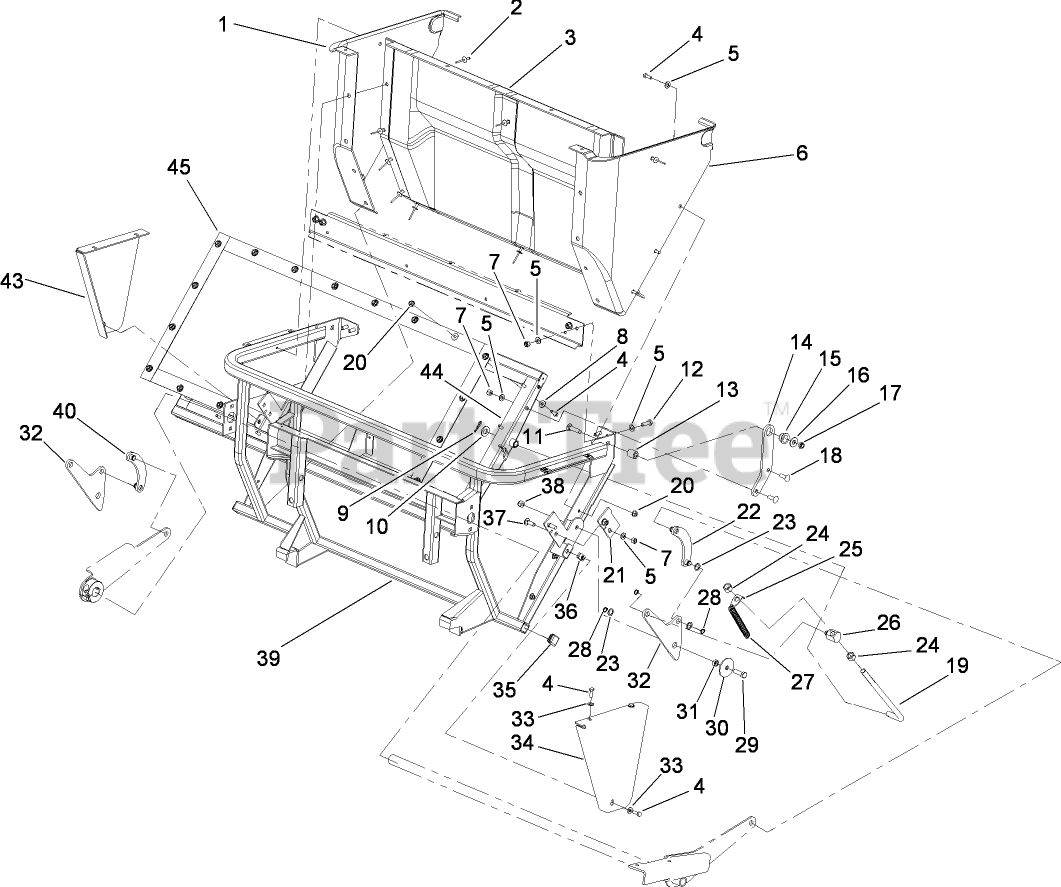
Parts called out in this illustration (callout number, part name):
1	PANEL-BAGGER, RH
2	RIVET-BLIND
3	PANEL-BAGGER
4	SCREW-HH
5	WASHER-PLAIN
6	PANEL-BAGGER, LH
7	NUT-LOCK, NI
8	WASHER-FLAT
9	PIN-COTTER
10	WASHER-FLAT
11	SCREW-CARR
12	SCREW-HH
13	PIN-PIVOT, HINGE
14	Plate, Hinge
15	Bearing
16	WASHER-FLAT
17	NUT-LOCK, NI
18	SCREW-CARR
19	LINK-DOOR
20	NUT-HF
21	STOP-LINKAGE
22	LINK-LH
23	WASHER-NYLON
24	NUT-HEX
25	ANCHOR-SPRING
26	TRUNNION-LINK
27	Spring
28	RING-RETAINING
29	SCREW-HH
30	Washer
31	BEARING-LINKAGE, PIVOT
32	ARM-LINKAGE, DOOR
33	WASHER-FLAT
34	GUARD-LH
37	BOLT-CARR
38	NUT-LOCK, NI
40	LINK-RH
43	GUARD-RH
44	DOOR-FRAME
45	SCREEN-DOOR
